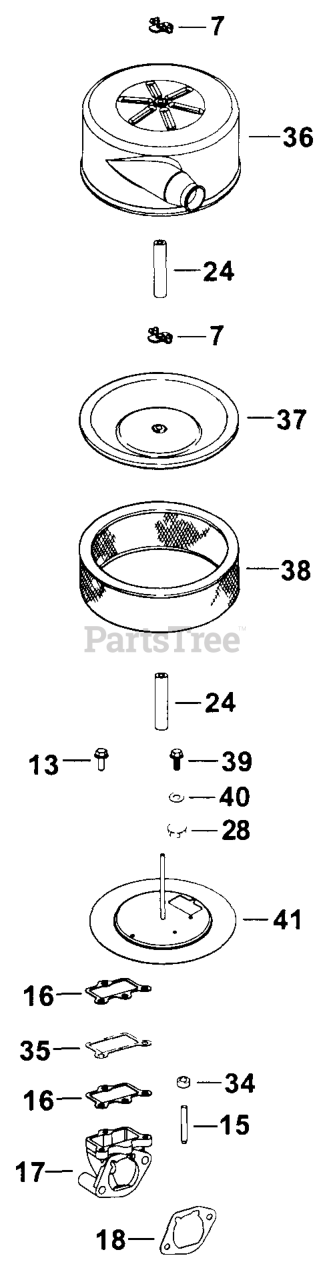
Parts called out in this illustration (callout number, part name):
7	NUT, WING
13	SCREW,FLG THD FRM M6X1.0X20-(#25086396S)
15	STUD, REMOTE AIR FILTER-DISCONTINUED
16	GASKET, AIR CLEANR BASE
17	ELBOW, AIR CLEANER
18	GASKET, AIR CLEANER BASE
28	NUT, FLG M6X1.0
35	SPACER, AIR CLEANER BASE
36	COVER, AIR CLEANER
37	COVER, INNER AIR CLEANER
38	ELEMENT, AIR CLEANER - Also available Retail Packaged 47 883 03-S1 Air Filter Kit
39	SCREW, FLG M6X1.0X10
41	BASE, AIR CLEANER - DISC.
